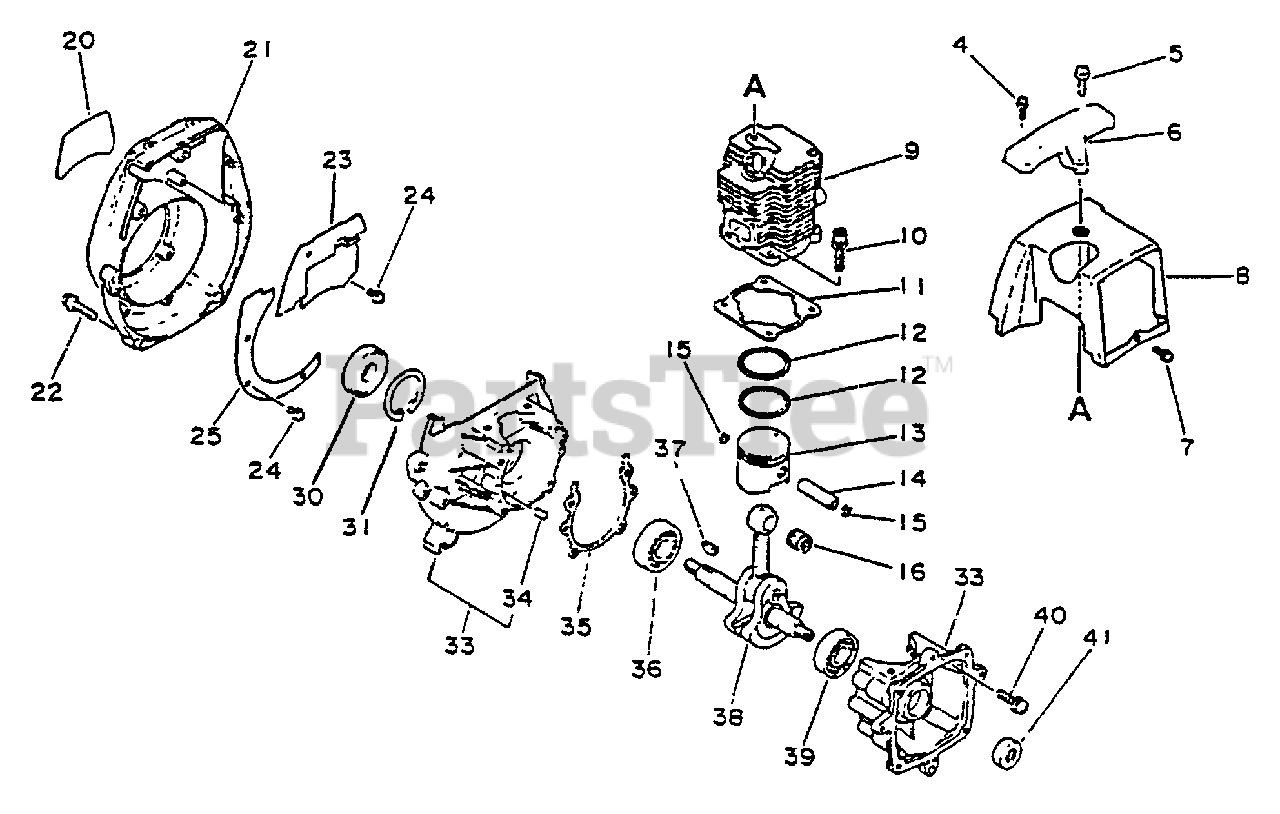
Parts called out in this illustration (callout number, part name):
4	SCREW - 4X14
5	SCREW - 5X16
6	GUARD - TOP
7	SCREW - 4X10
8	COVER, ENGINE - ORANGE
9	CYLINDER
10	SCREW - 5X20
11	GASKET, CYLINDER
12	RING, PISTON
13	PISTON
14	PIN, PISTON
15	RING, RETAINING
16	BEARING, NEEDLE
20	LABEL - MODEL
21	COVER, ENGINE - ORANGE
22	SCREW - 5X20
23	SHIELD, FAN
24	SCREW - 4X5
25	SHIELD, FAN
30	SEAL, OIL
31	RING, RETAINING - 32
33	CRANKCASE KIT
34	PIN - LOCATING
35	GASKET, CRANKCASE
36	BEARING, BALL - 6201
38	CRANKSHAFT ASSY
39	BEARING, BALL - 6001C3
40	SCREW - 5X25
41	SEAL, OIL
